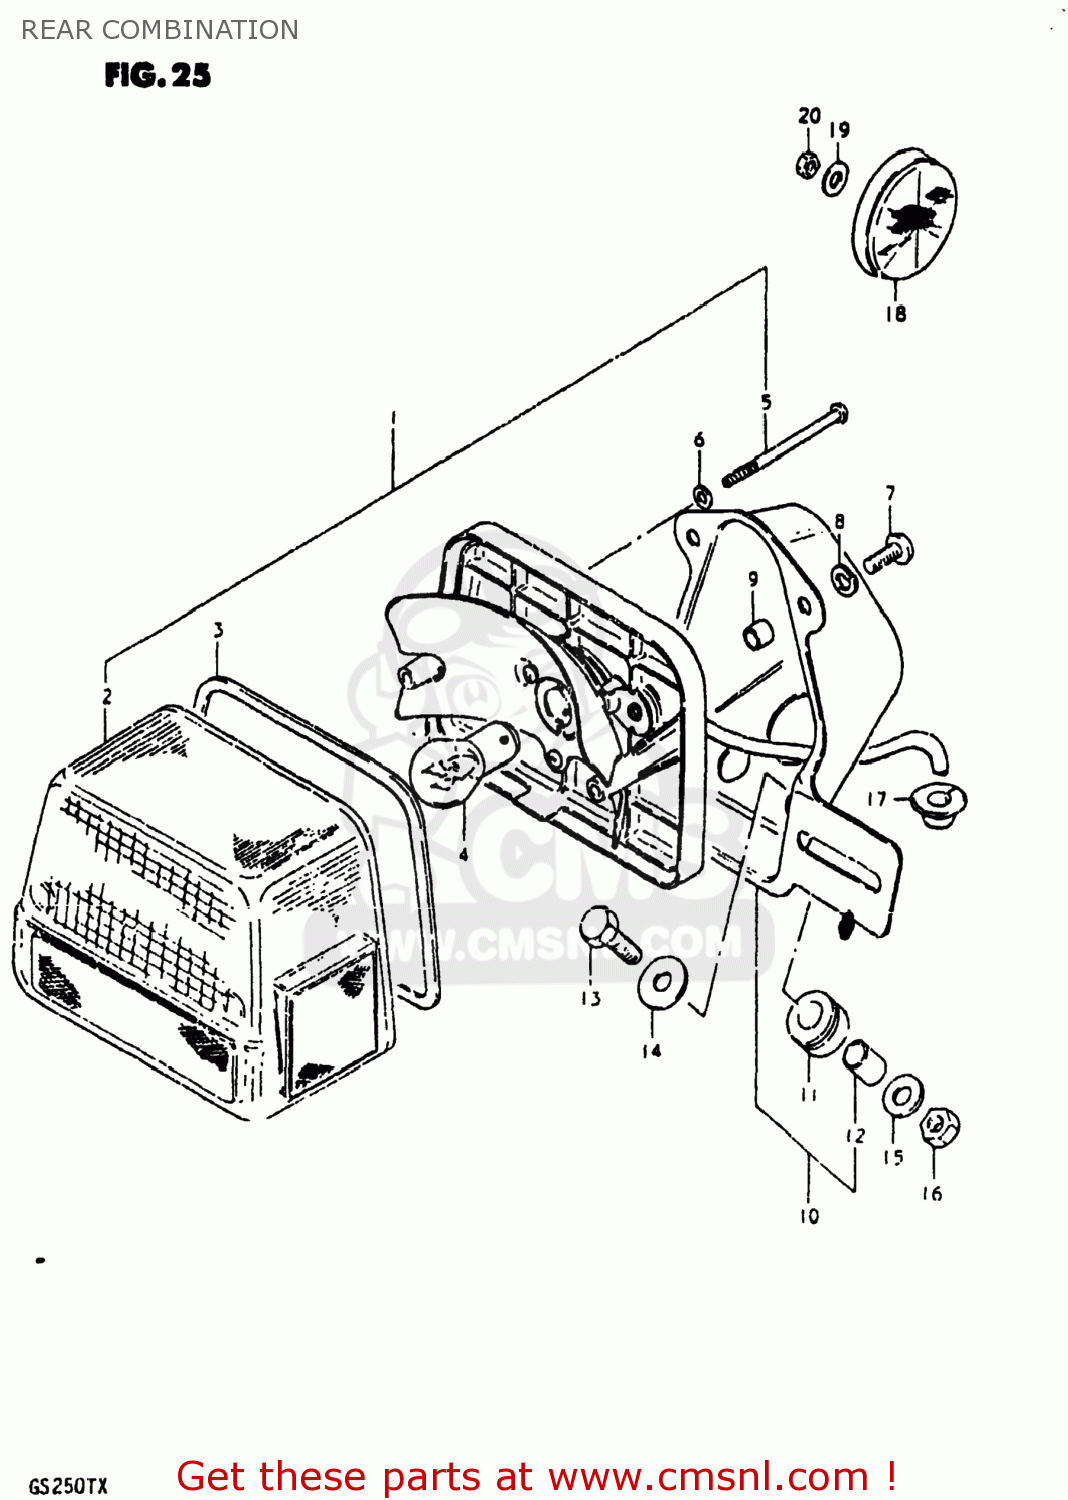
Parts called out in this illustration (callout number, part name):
1	LAMP UNIT,REAR COMBINATION
2	LENS
3	GASKET (NAS)
4	BULB(12V23W)
5	SCREW
6	GASKET (NAS)
7	SCREW
8	LOCK WASHER
9	SPACER
10	BRACKET UNIT,TAIL LAMP
11	CUSHION
12	SPACER
13	BOLT
14	WASHER (6.5X20X1.2)
15	WASHER
16	NUT
17	GROMMET
18	REFLEX REFLECTOR,FR
19	WASHER
20	LOCK WASHER
